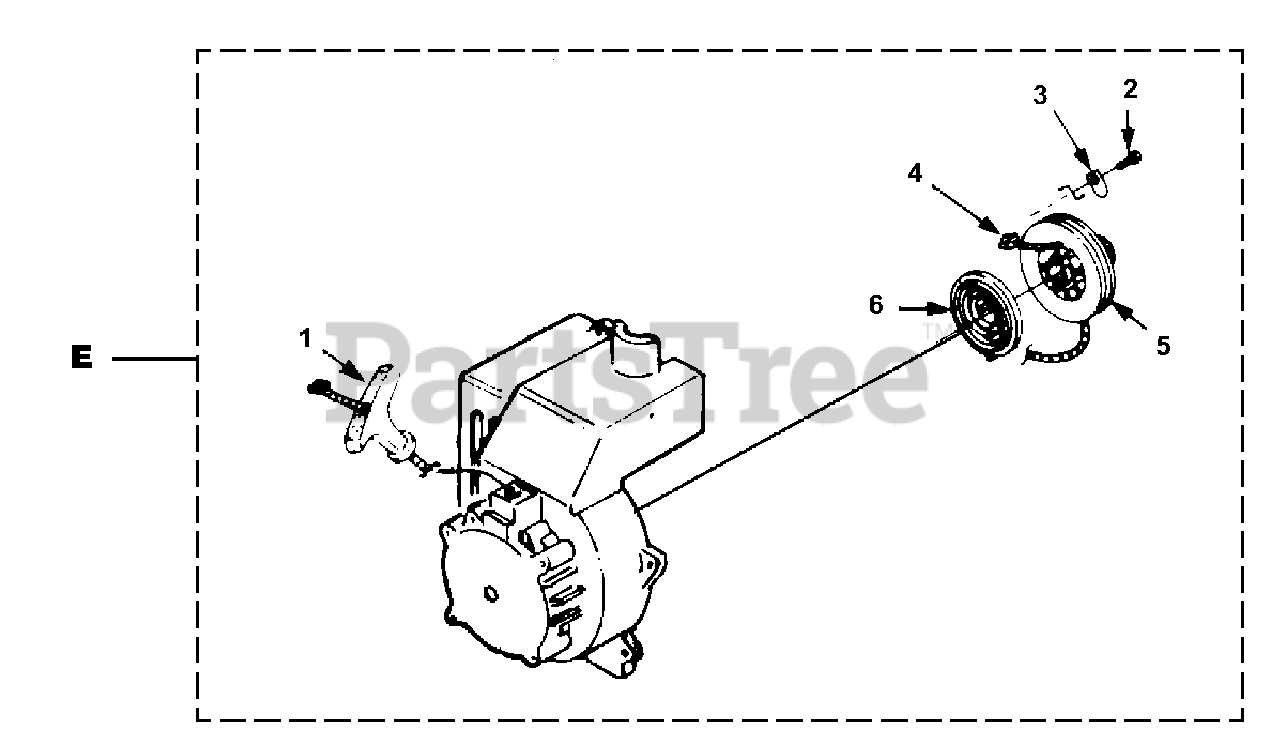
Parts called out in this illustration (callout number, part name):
1	GRIP-Starter
2	SCREW-Thread Form. (#10 X 1/2")
3	BRACKET-Retaining
4	ROPE-Starter
5	PULLEY-Starter
6	SPRING & CONTAINER
E	ENGINE HOUSING & DECAL KIT
